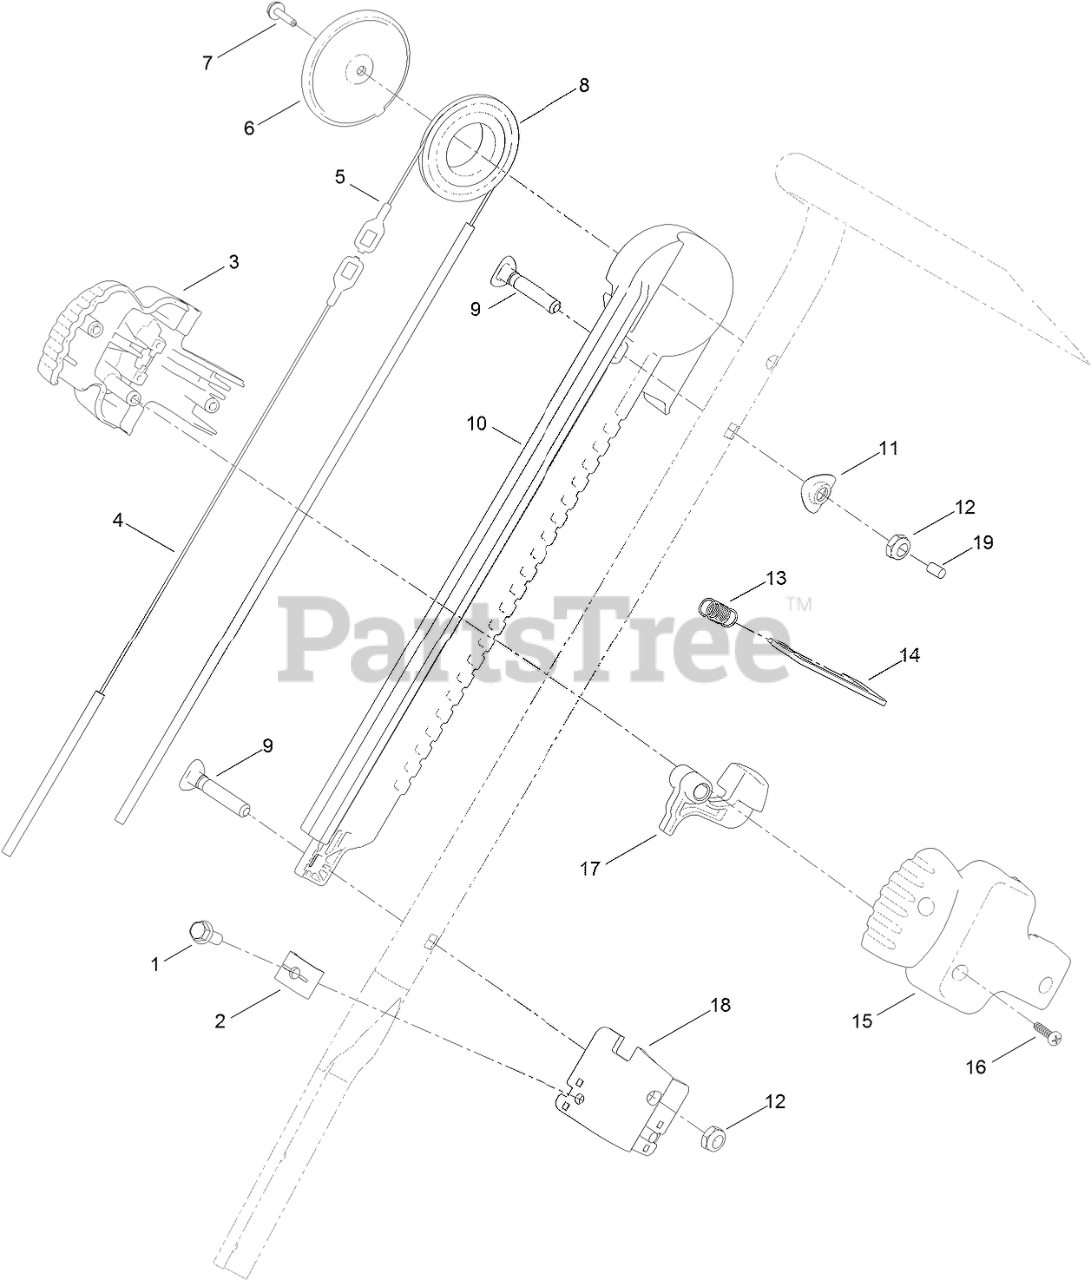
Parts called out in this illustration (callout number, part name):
1	SCREW-HWH
2	CLAMP-CABLE
3	HANDLE-SLIDER, RH
4	CABLE-CHUTE, SHORT
5	CABLE-CHUTE, LONG
6	COVER-PULLEY
7	SCREW-HWH
8	PULLEY-SLIDER
9	SCREW-HANDLE
10	TRACK-SLIDER
11	WASHER
12	NUT-LOCK, NI
13	SPRING-TRIGGER
14	PLATE-LOCK, CHUTE
15	HANDLE-SLIDER, LH
16	SCREW-PPH
17	TRIGGER
18	BRACKET-CABLE
19	CAP-THREAD, SCREW
